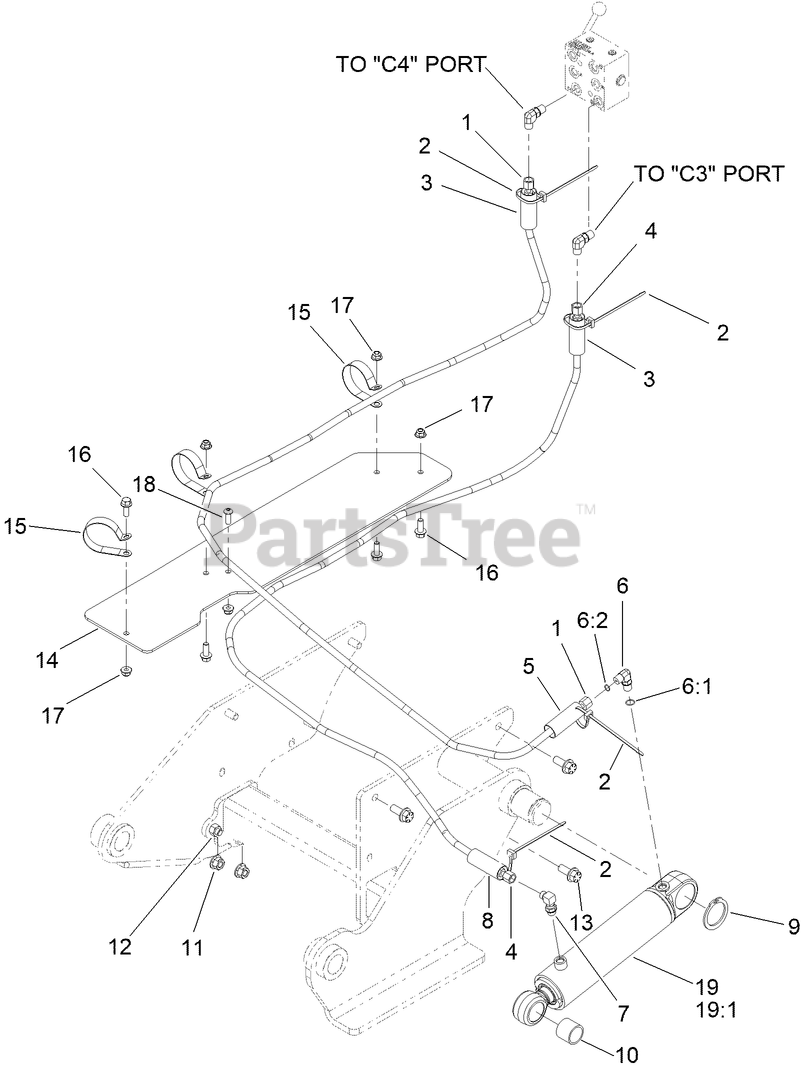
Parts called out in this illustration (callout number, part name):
1	HOSE (04OFX-90"-3000)
2	TIE-CABLE
3	ABRASION SLEEVE (1.00" X 24")
4	HOSE (04OFX-80"-3000)
5	ABRASION SLEEVE (1.00" X 22")
6	FITTING-ELBOW, 90 DEG
6:1	O-RING
6:2	O-RING
7	CONNECTOR (04O-06S90, .091 ORF)
8	ABRASION SLEEVE (1.00" X 14")
9	RING-RETAINING, EXTERNAL
10	COMPOSITION BUSHING (1.25")
11	NUT-LOCK
12	SCREW-HHF
13	SCREW-HHF
14	PLATE - EXTEND
15	P-CLAMP (2 1/2" DIA.)
16	SCREW-HHF
17	NUT-HF, NI
18	SCREW-HSBH
19	CYL (2.5 X 1.25 X 8.0)
19:1	SEAL REPAIR KIT
